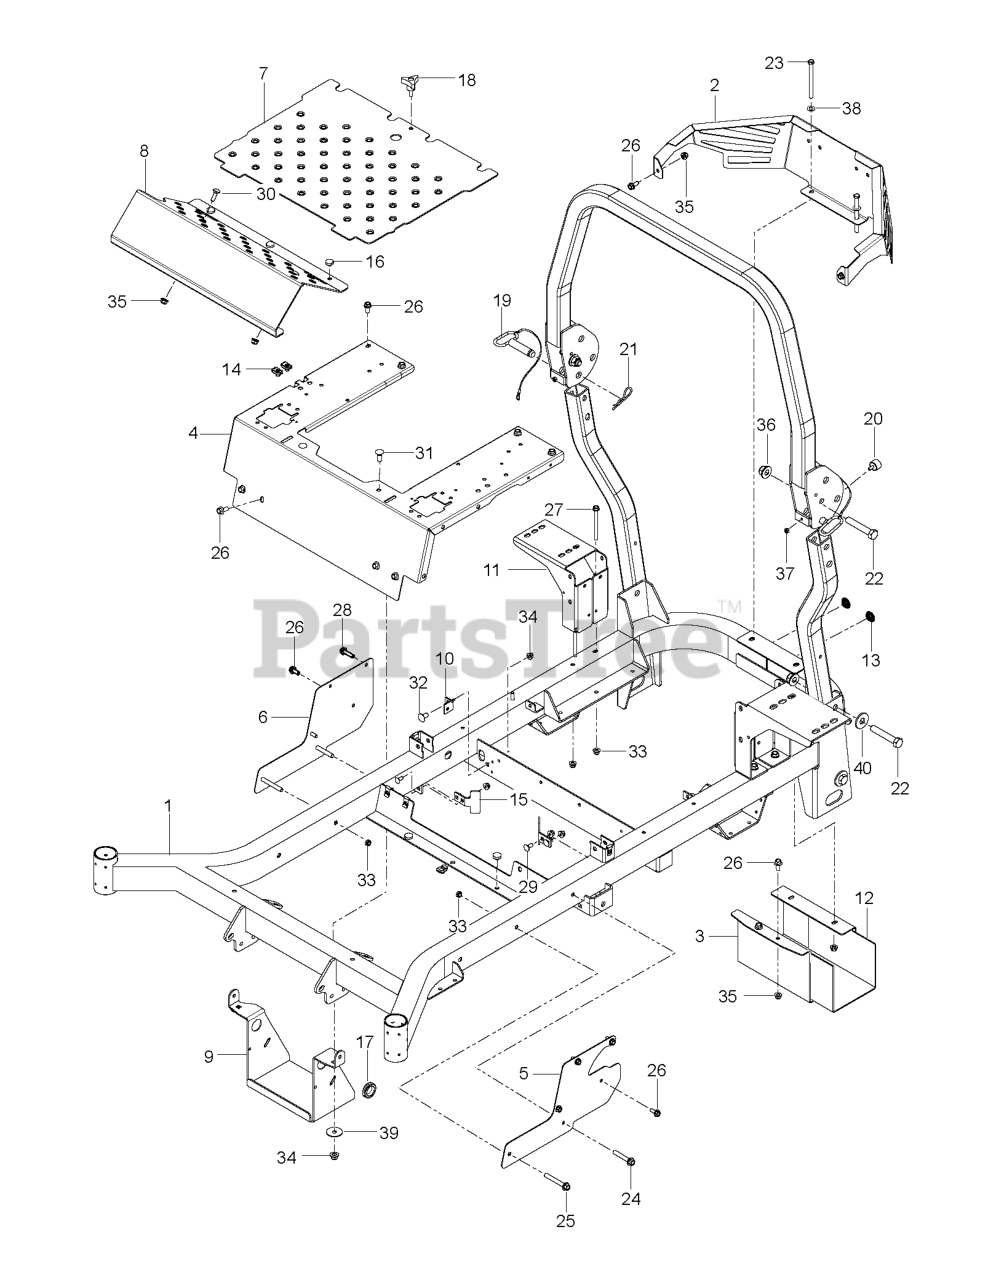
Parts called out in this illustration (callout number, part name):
1	FRAME.KIT.W/DECALS.REDMAX.672
2	GUARD.REAR.PAINT.SNAP.RED.672
3	SHIELD, MUFFLER
4	SUPPORT SEAT CONTROL SNAPPER R
5	BRACKET SIDE LH SNAPPER RED X6
6	BRACKET SIDE RH SNAPPER RED X6
7	KIT.PLATE.FLOOR.W/DCL.REDM.672
8	PLATE.FOOTREST.PNT.G-BLACK
9	BRACKET.PNT.BATTERY.BLK
10	BRACKET.DAMPENER.BLACK
11	MOUNT, TANK, ZT BLK
12	HEAT SHIELD
13	CAP.PLUG.BP-1.BLACK
14	U-CLIP 5/16-18 NUT RETAINER
15	STOP, DECK, EZ+
16	GROMMET, BUMPER
17	RUBBER GROMMET
18	KNOB W/STUD
19	PIN, ROPS
20	BUMPER, MALE STUD, 1/4-20
21	PIN HAIR .148 X 2-15/16 #210
22	5/8-11 X 3-1/2 HHB GRADE 5
23	HCS 5/16C X 4
24	HHFS 3/8-16 X 2.5 GR 5 ZD
25	HHFS 3/8-16 X 2-3/4 GR5 ZD
26	HHFS 5/16-18 X 3/4
27	BOLT.HEX.FLNG.5/16-18X3.75
28	HHFS 5/16-18 X 1.25 TPBLT GD 5
29	BOLT 5/16C X 3/4" CARRIAGE
30	RHSNB 5/16C X 1
31	RHSNB 3/8C X 1
32	RHSNB 5/16-18 X 3/4
33	NUT HEX 3/8-16 NYLON, THIN
34	NUT 3/8-16 HEX FLG NYLOC ZD
35	5/16-18 NYLOC FLANGE NUT
36	NUT 5/8-11 FLG NYLOC ZD
37	RP_NUT 1/4-20 NYLOC
38	WASHER
39	WASHER.13/32X1-1/2X16GA
40	WASHER, 5/8 FLAT
